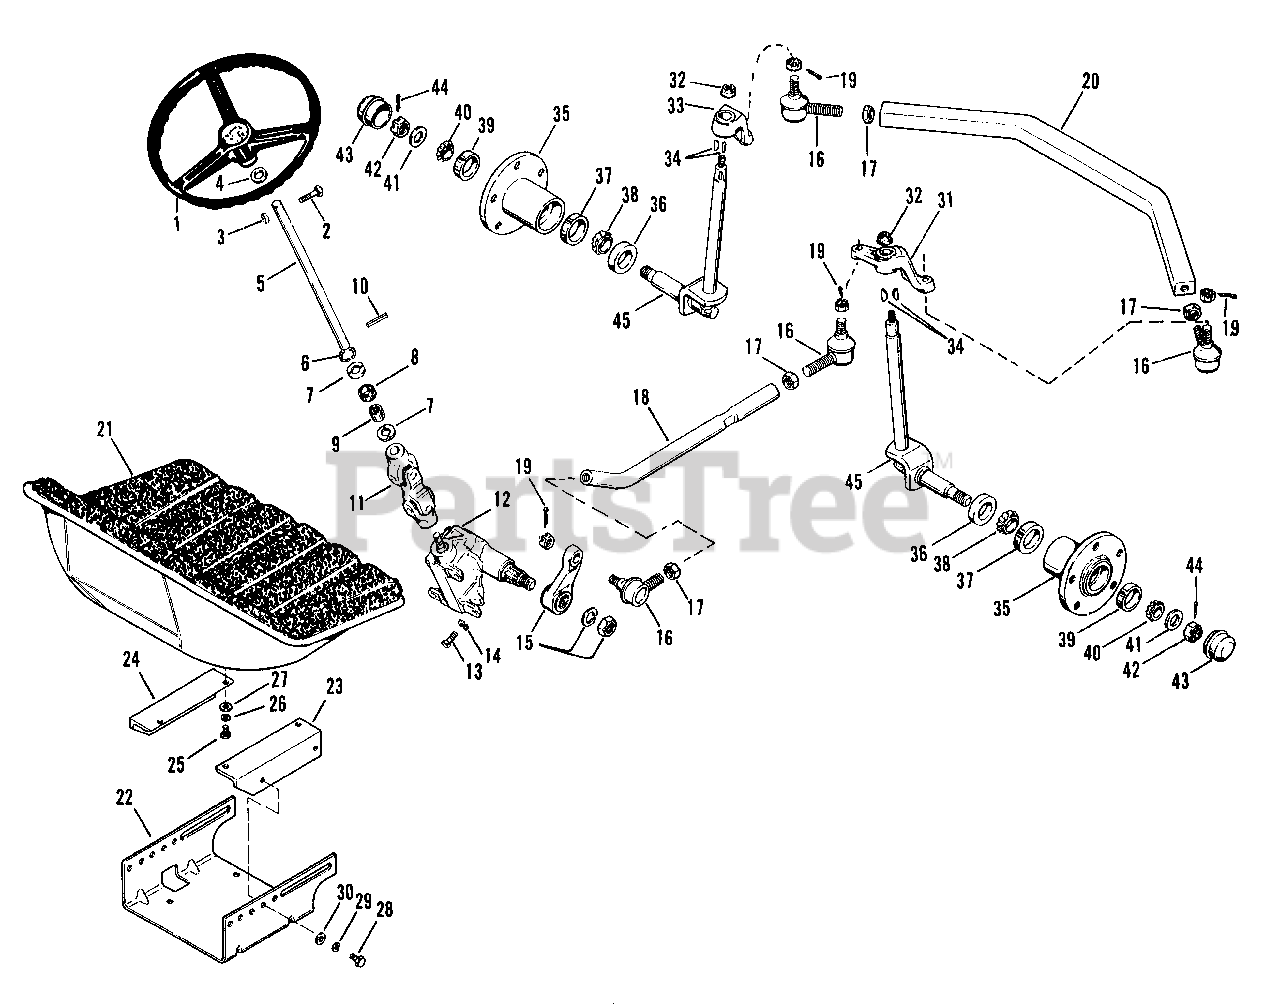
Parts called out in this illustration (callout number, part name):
1	Steering Wheel
2	Hex Capscrew, 5/16"-18 x 1-1/4" lg.
3	Hex Nut, Lock, 5/16"-18
5	Steering Shaft
6	Retaining Ring
7	Thrust Washer
8	Roller Bearing
9	Needle Bearing
10	Roll Pin, 3/8"x 1-1/4" lg.
11	"U" Joint
12	Steering Gear
13	Hex Capscrew, 7/16"-14 x 1" lg.
14	Lock Washer, 7/16"
15	Pitman Arm
17	Hex Nut, Jam
18	Drag Link
19	Cotter Pin
23	Seat Bracket, R.H.
24	Seat Bracket, L.H.
25	Hex Capscrew, 5/16"-18 x 3/4" lg.
26	Lock Washer, 5/16"
27	Plain Washer, 5/16"
28	Hex Capscrew, 3/8"-16 x 5/8" lg.
29	Lock Washer, 3/8"
30	Plain Washer, 3/8"
31	Steering Arm, R.H.
32	Lock Nut, Washer Base
33	Steering Arm, L.H.
35	Hub Assembly
37	Bearing Cup
38	Bearing Cone
39	Bearing Cup
40	Bearing Cone
41	Thrust Washer
42	Slotted Nut
43	Grease Cap
44	Cotter Pin
45	Spindle Assembly
